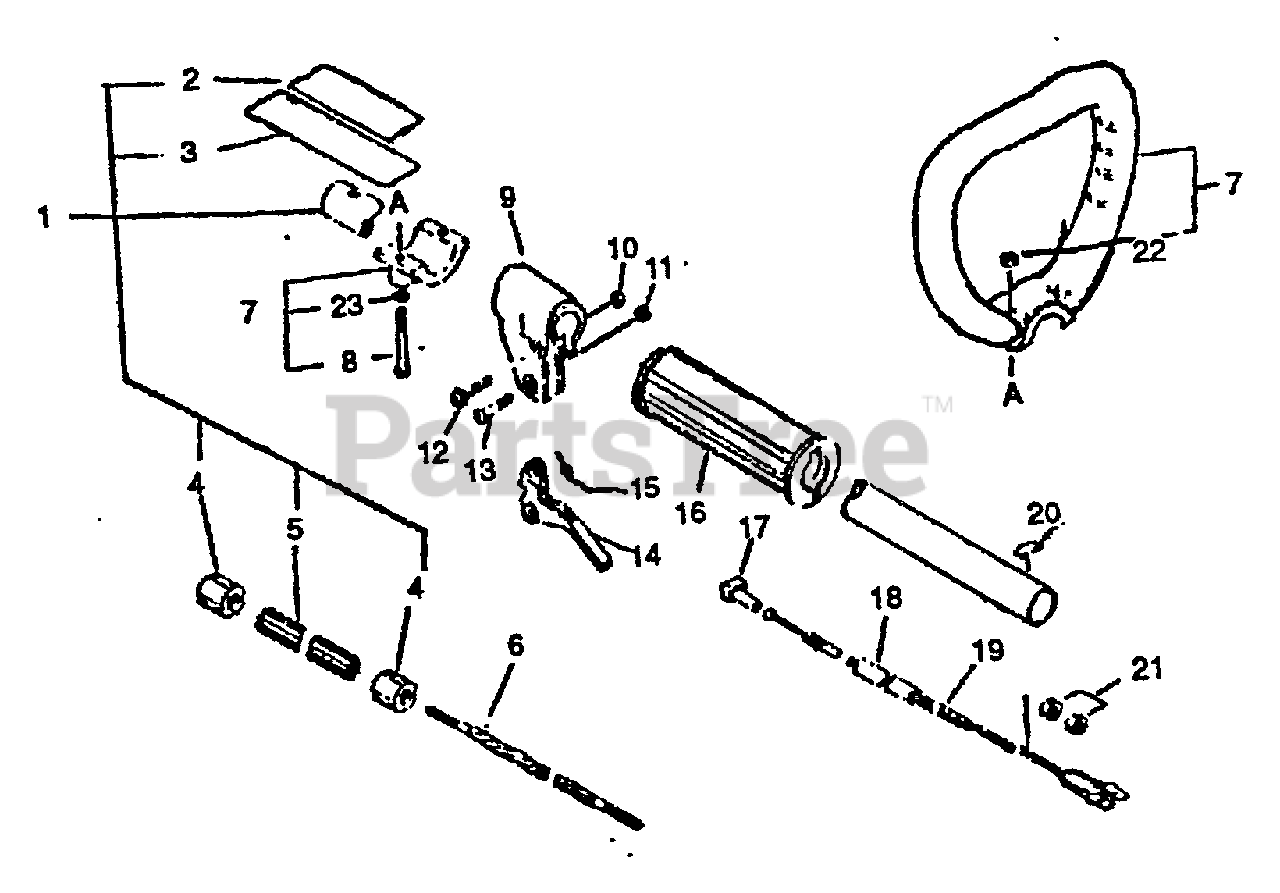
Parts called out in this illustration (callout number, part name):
1	MAIN PIPE ASSY
2	LABEL - CAUTION
3	LABEL - CAUTION
5	LINER - FLEXIBLE
6	DRIVESHAFT - FLEXIBLE
7	LOOP HANDLE ASSY
8	SCREW 5×40
9	BRACKET, TRIGGER
10	NUT M5
11	WASHER, SPRING 5
12	SCREW 5×30
14	TRIGGER, THROTTLE
15	SPRING, THROTTLE
16	GRIP
17	GUIDE, CABLE
19	CABLE, THROTTLE
20	LABEL - ALIGNMENT
22	NUT M5
23	WASHER, FLAT 5.5×10×0.8
